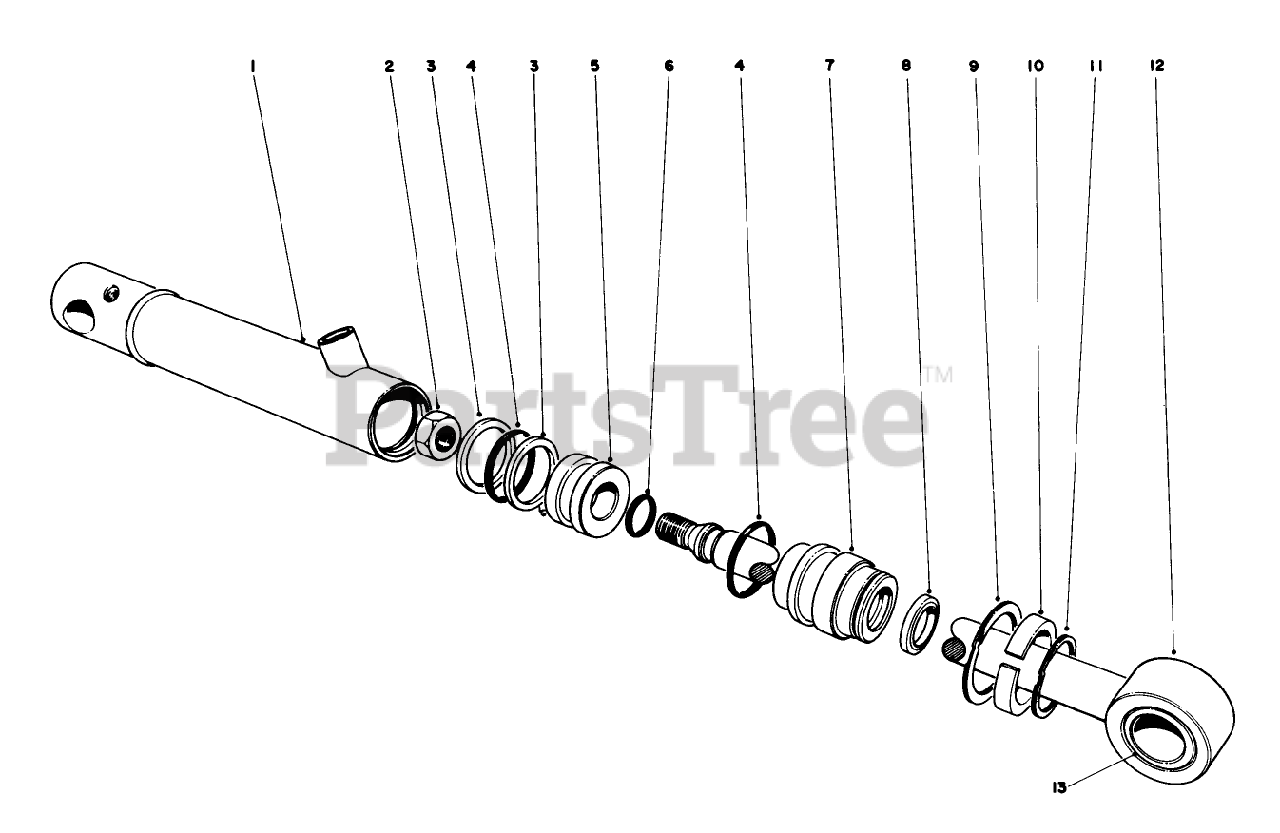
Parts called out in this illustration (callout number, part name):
1	Tube Assembly
2	Jam Nut
3	Back Up Washer
4	O-Ring Piston
5	CYL PISTON
6	Seal Rod
7	Head Assembly
8	Rod Wiper
9	Lock Ring Head
10	SPACER
11	OUTER LOCK RING
12	CYL PISTON ROD
13	Bushing
